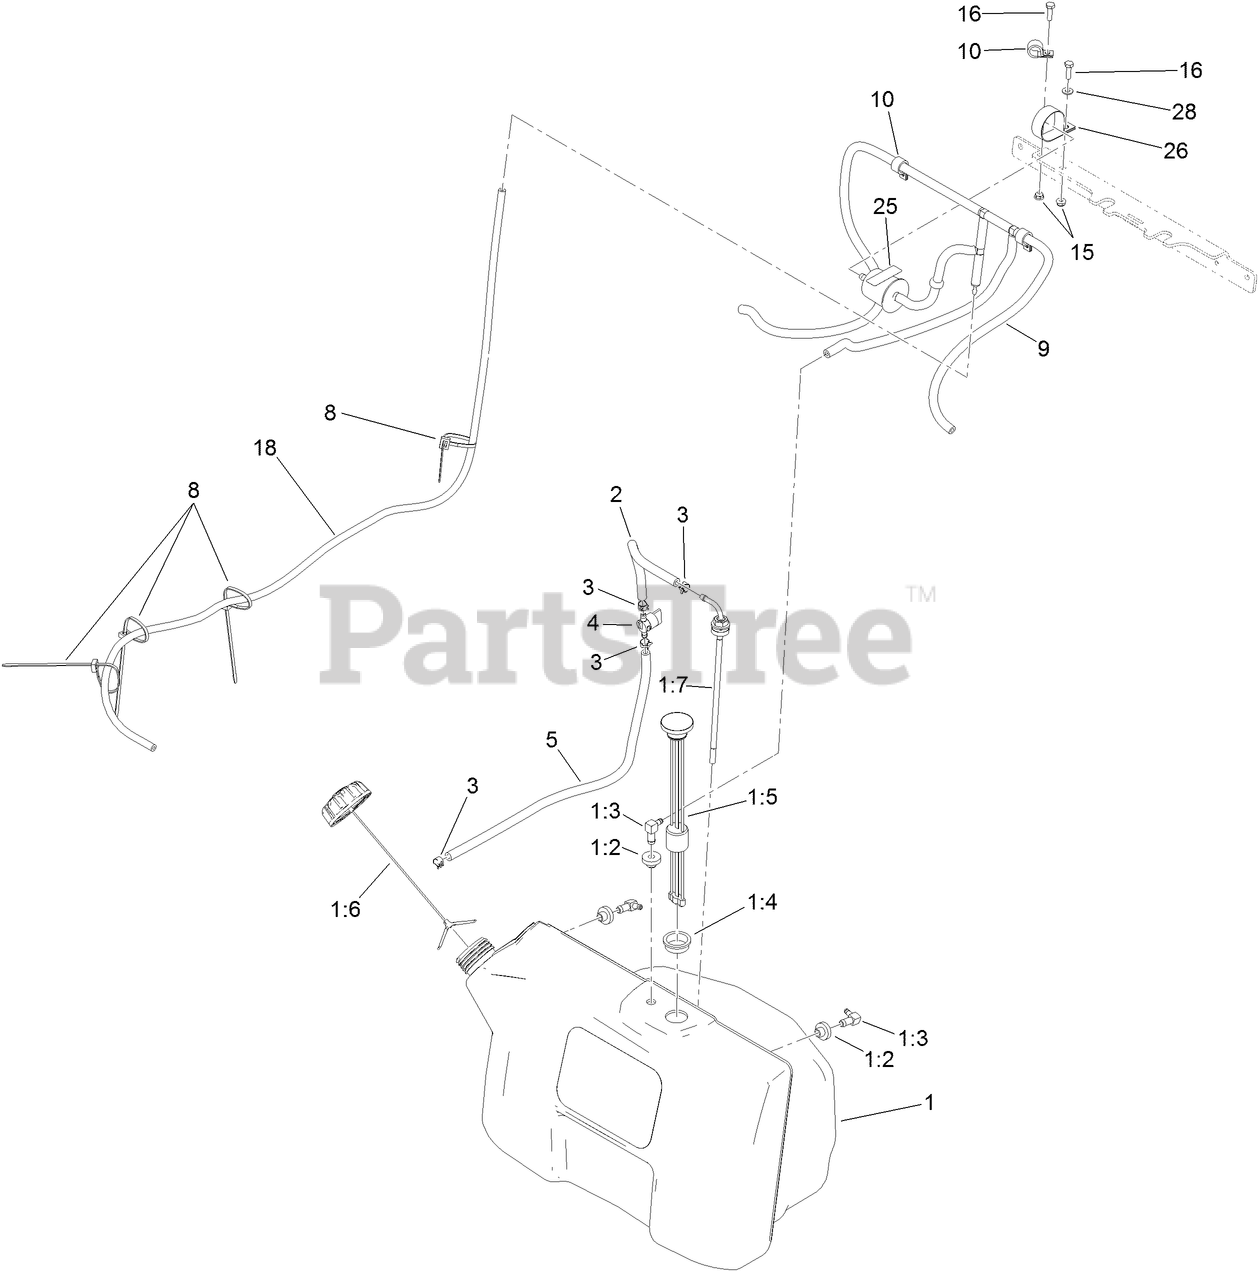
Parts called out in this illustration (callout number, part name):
1	TANK ASM
1:2	BUSHING
1:3	ELBOW-90 DEG
1:4	GROMMET
1:5	GUAGE-FUEL
1:6	CAP-FUEL, RATCHETING
1:7	FITTING-FUEL, BULKHEAD
2	HOSE-FUEL
3	CLAMP-HOSE
4	VALVE-FUEL
5	HOSE-FUEL
8	TIE-CABLE
9	VENT HOSE ASM
10	CLAMP-CABLE
15	NUT-HF
16	SCREW-HH
18	HOSE-FUEL
25	DECAL-FILTER, EMISSIONS
26	CLAMP-R
28	WASHER-FLAT
